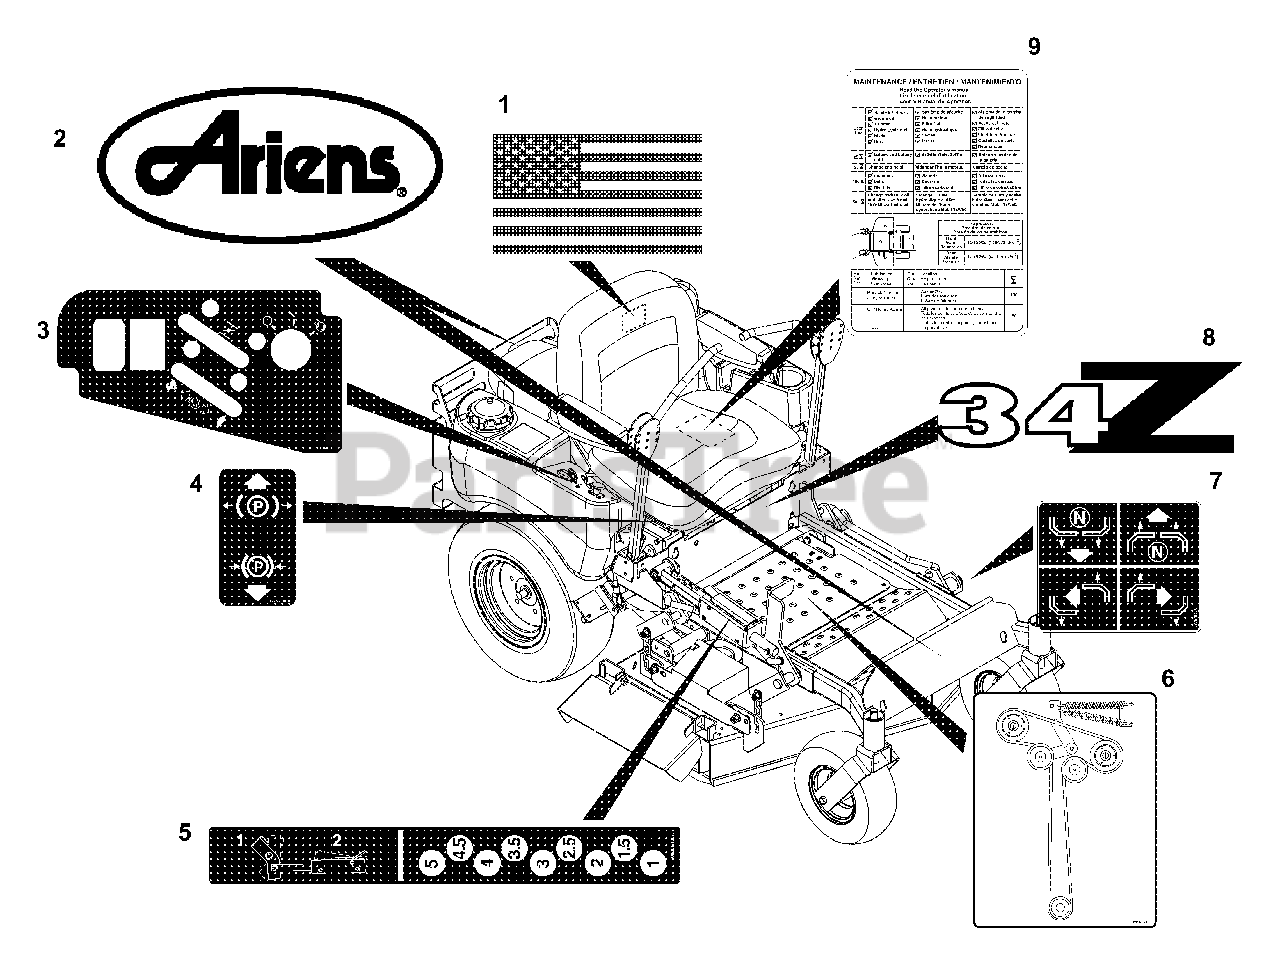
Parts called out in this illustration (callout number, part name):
1	DECAL, AMERICAN FLAG
2	DECAL, ARIENS
3	DECAL, CONTROL PANEL COMPACT Z
4	DECAL, PARKING BRAKE LEVER
5	DECAL, HEIGHT OF CUT COMPACT-Z
6	DECAL, BELT DIAGRAM COMPACT-Z
7	DECAL, INSTRUCTIONAL-STEERING
8	DECAL, STYLE COMPACT-Z
9	DECAL, MAINTENANCE INSTRUCTION
